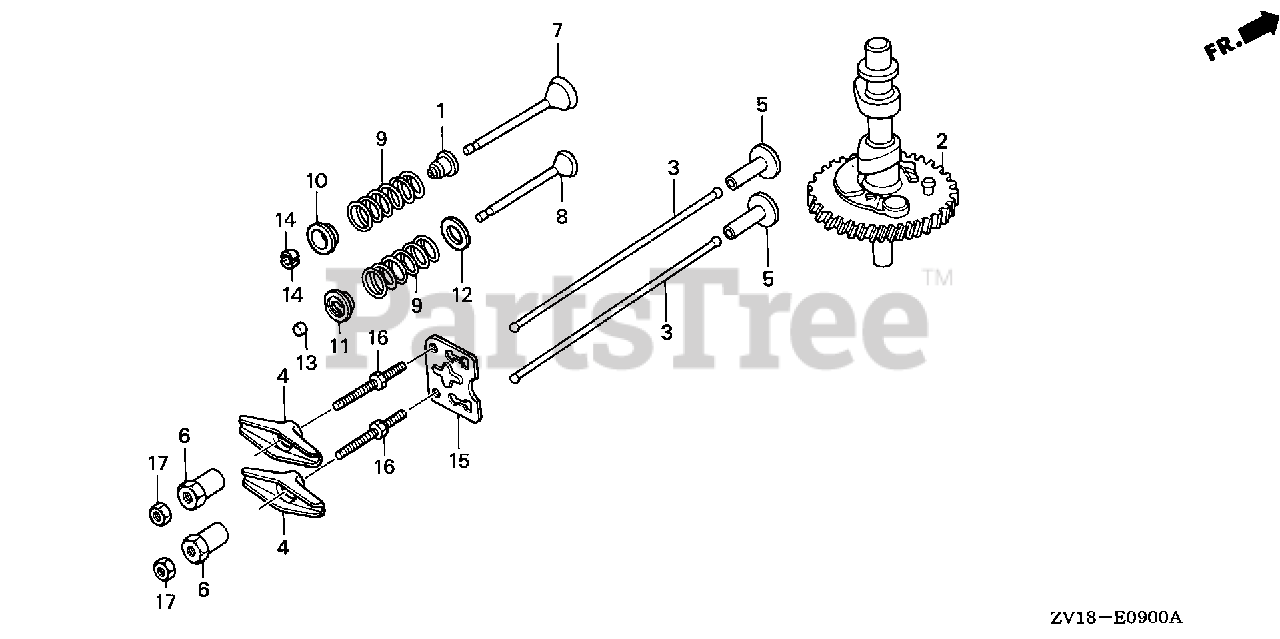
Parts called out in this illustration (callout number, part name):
1	SEAL, VALVE STEM
2	CAMSHAFT (NOT AVAILABLE)
4	ARM, VALVE ROCKER
5	LIFTER, VALVE
6	PIVOT, ROCKER ARM
7	VALVE, IN.
8	VALVE, EX.
9	SPRING, VALVE
10	RETAINER, VALVE SPRING
11	RETAINER, EX. VALVE SPRING
12	SEAT, VALVE SPRING
13	ROTATOR, VALVE
14	COTTER, VALVE (SANKO)
15	PLATE, PUSH ROD GUIDE
16	BOLT, PIVOT (8MM)
17	NUT, PIVOT ADJUSTING
